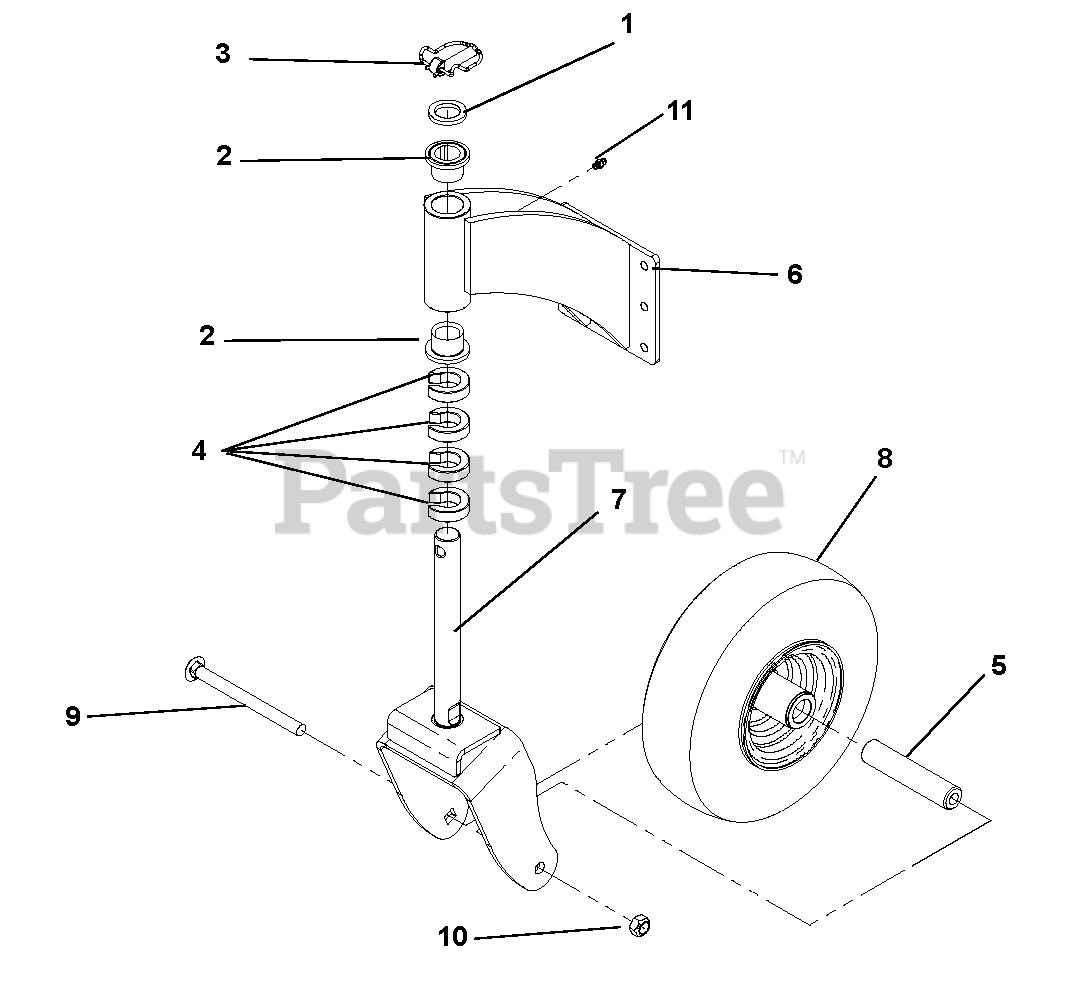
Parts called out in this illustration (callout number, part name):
1	Bushing, 1.03 x 1.50 x .179
2	Bearing, FLG 1.00 x 1.25 x 1.00
3	Pin, Lock .438 x 2.00
4	C-Spacer, 1.00 x 1.77 x .50 (48-inch Decks)
5	Tube, 1.00 x .50 x 4.76
6	Weldment, Caster Mount Bracket (48-inch Decks)
7	Weldment, Front Wheel Fork (48-inch Decks)
8	Wheel, Front 11 x 4 x 5
9	Bolt, Round Head Square Neck .50-13 x 6.00
10	Nut, Locking-Cone Grade C
11	Grease Zerk, 1/4-28 STR .69 LG
